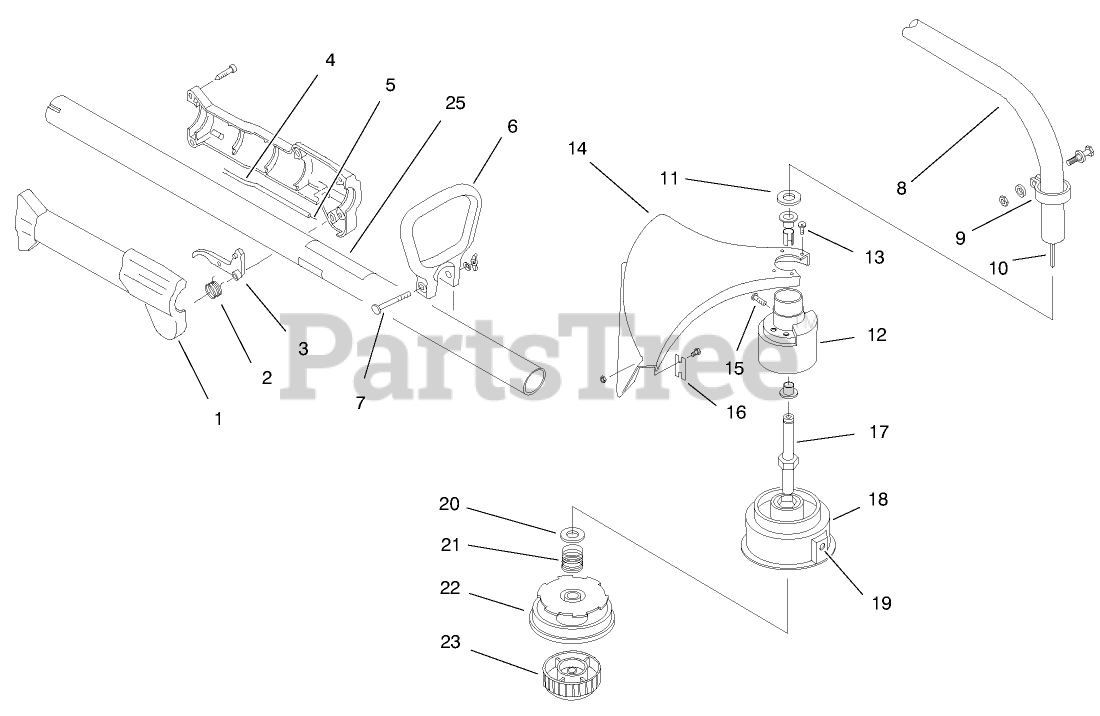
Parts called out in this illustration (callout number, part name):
1	Throttle Housing & Trigger Asm.
2	SPRING - TRIGGER
3	HSG - THROTTLE TRIGGER
4	Throttle Cable Housing
5	Throttle Cable
6	D-Handle
7	HARDWARE - D-HANDLE
8	DRIVE SHAFT HSG ASM
9	CLAMP ASM - UPPER
10	SHAFT - FLEX, 48.94
12	BUSHING HSG ASM
13	Guard Mounting Screw
14	Guard and Blade Asm. (Incl. Ref. #16)
15	Anti-Rotation Screw
16	BLADE ASM
17	Shaft-Spool
18	OUTER SPOOL EYELET ASM
19	EYELET
20	RETAINER ( 10 PACK)
21	SPRING
22	REEL - INNER
23	SMALL BUMP KNOB ASM
25	DECAL - SAFETY SYMBOLS
